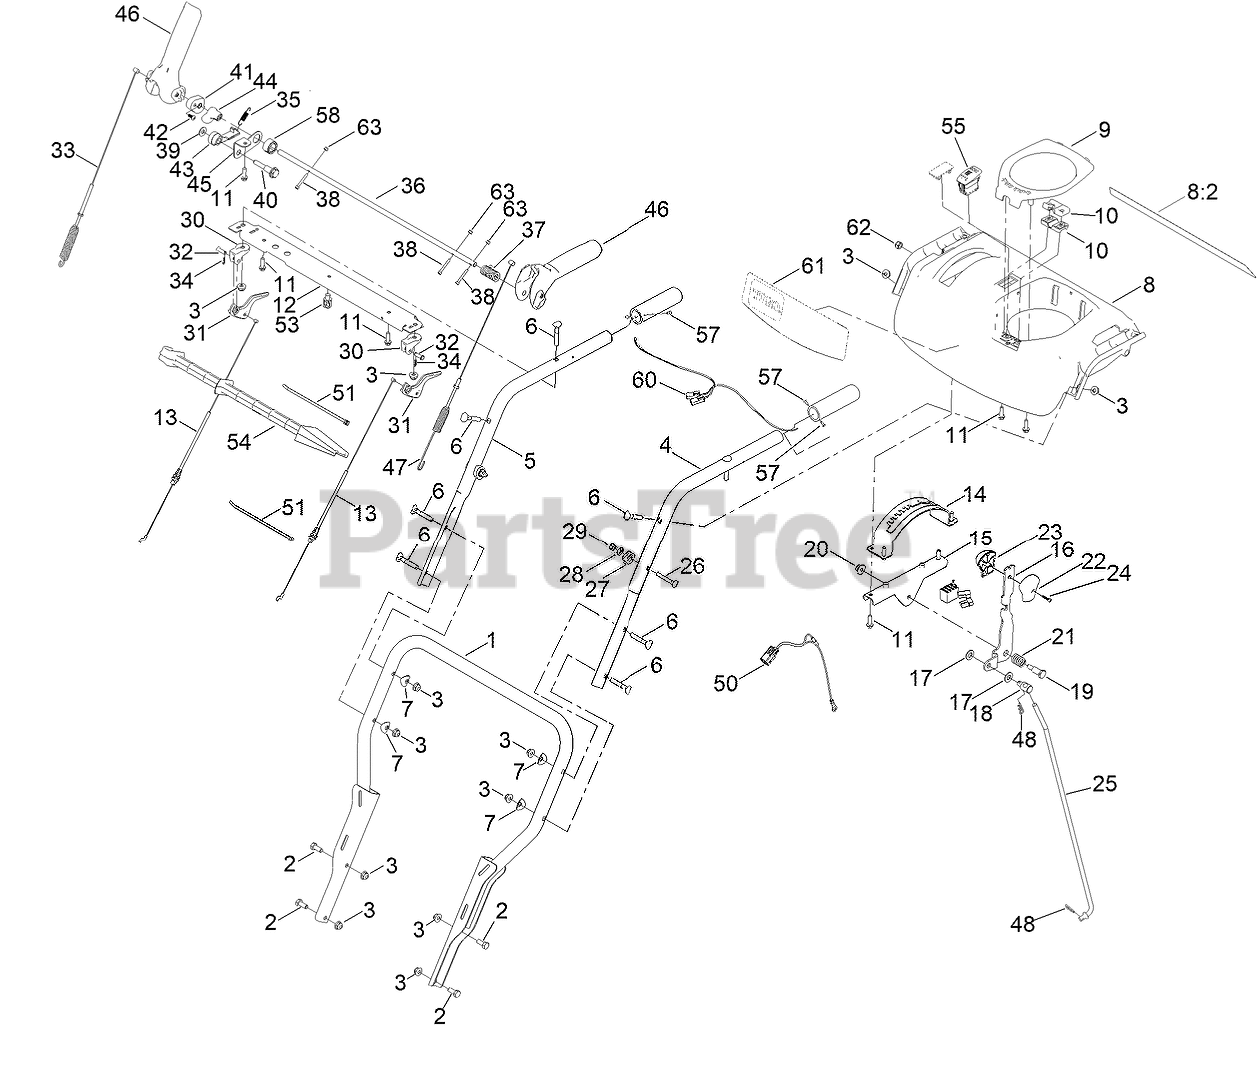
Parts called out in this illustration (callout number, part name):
1	LOWER HANDLE ASM
2	SCREW-HH
3	NUT-HF
4	HANDLE-UPPER, LH
5	HANDLE-UPPER, RH
6	SCREW-HANDLE
7	WASHER-CUP
8	PANEL-CONTROL
8:2	DECAL-SAFETY
9	COVER-QUICKSTICK
10	SUPPORT-ROD
11	SCREW-PLASTITE, HWH
12	BRACE-CONSOLE
13	CABLE-CLUTCH
14	GATE-SHIFT
15	BRACKET-SHIFT
16	SELECTOR-SPEED
17	WASHER-FLAT
18	TRUNNION-ROD
19	SCREW-SHOULDER, HH
20	NUT-HF
21	SPRING-COMPRESSION
22	KNOB-SHIFT, LH
23	KNOB-SHIFT, RH
24	SCREW-PPH
25	ROD-SHIFT
26	BOLT-CARR
27	CLAMP-CABLE
28	WASHER-FLAT
29	NUT-HEX
30	MOUNT-LEVER, CLUTCH
31	LEVER-CLUTCH
32	PIN-CLEVIS
33	CABLE-AUGER
34	PIN-HAIR
35	SPRING-LOCKOUT, HANDLE
36	ROD-LOCKOUT
37	SPRING-TORSION, HANDLE RETURN
38	SCREW-HSH
39	WASHER-FLAT
40	SCREW-SHOULDER
41	LOCK-HANDLE
42	SCREW-PPH
43	LATCH-LOCKOUT
44	CAM-LOCKOUT
45	LINK-LOCKOUT
46	LEVER-CONTROL
47	CABLE-TRACTION
48	PIN-HAIR
50	HARNESS-WIRE, LED AND HAND WARMERS
51	TIE-CABLE
53	CLIP-TIE
54	STICK-CLEANOUT
55	SWITCH-ROCKER, ON-NONE-OFF (HEATER)
57	RIVET-POP
58	COLLAR-CAM
60	GRIP-HEATED
61	DECAL-CONSOLE
62	NUT-HEX
63	NUT-LOCK ROHS
